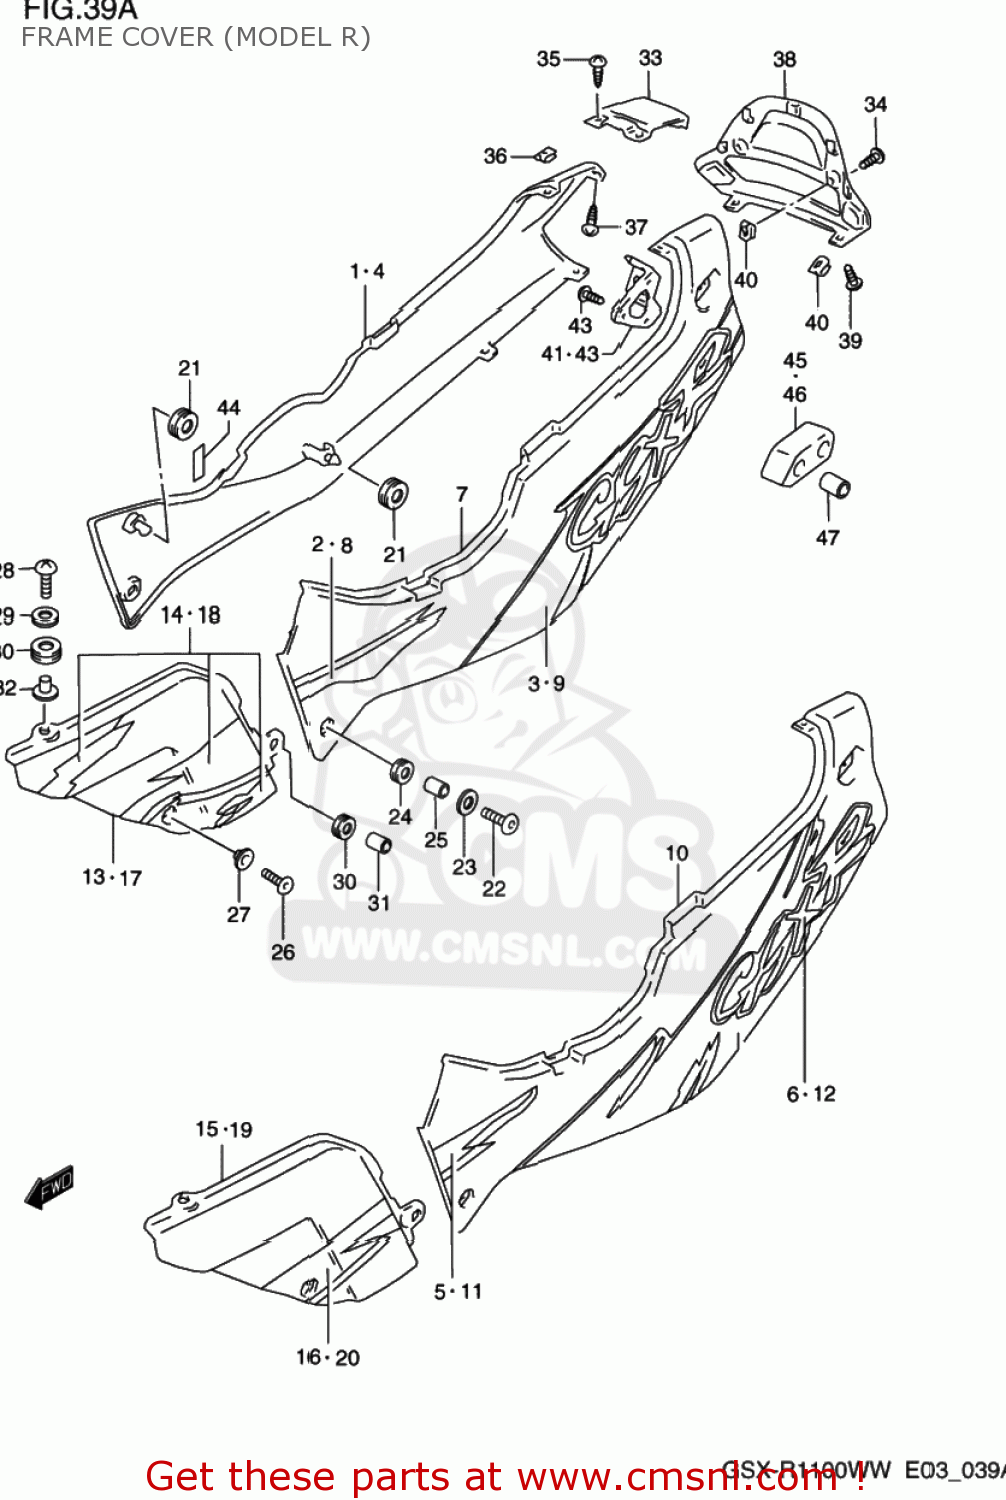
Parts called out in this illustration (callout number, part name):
1	COVER ASSEMBLY,FRAME,RIGHT
2	TAPE,FRAME COVER STRIPE
3	EMBLEM,FRAME COVER,R
4	COVER ASSEMBLY,FRAME,RIGHT
5	TAPE,FRAME COVER STRIPE
6	EMBLEM,FRAME COVER,R
7	COVER ASSEMBLY,FRAME,LEFT
8	TAPE,FRAME COVER STRIPE
9	EMBLEM,FRAME COVER,LEFT
10	COVER ASSEMBLY,FRAME,LEFT
11	TAPE,FRAME COVER STRIPE
12	EMBLEM,FRAME COVER,L
13	COVER ASSEMBLY,FRAME BODY
14	TAPE SET,FRAME COVER B
15	COVER ASSEMBLY,FRAME BODY
16	TAPE,FRAME COVER BODY
17	COVER ASSEMBLY,FRAME BODY
18	TAPE SET,FRAME COVER BODY,L
19	COVER ASSEMBLY,FRAME BODY
20	TAPE,FRAME COVER BODY,L
21	CUSHION
22	SCREW(6X30)
23	WASHER
24	CUSHION
25	SPACER (6.1X9X9)
26	SCREW(5X14)
27	WASHER
28	SCREW
29	WASHER (6.5X18X1.6)
30	CUSHION
31	SPACER (6.1X9X9)
32	WASHER
33	COVER ASSY,FRAME CTR
34	SCREW(5X12)
35	SCREW 5X12
36	NUT
37	SCREW
38	COVER,FRAME RR
39	SCREW(5X12)
40	NUT
41	BRACKET,RR COMBINATION LAMP,L
42	BRACKET,RR COMBINATION LAMP,L
43	SCREW
44	CUSHION
45	CUSHION,PILLION RIDER HANDLE,R
46	CUSHION,PILLION RIDER HANDLE,L
47	SPACER (8.5X16X37)
